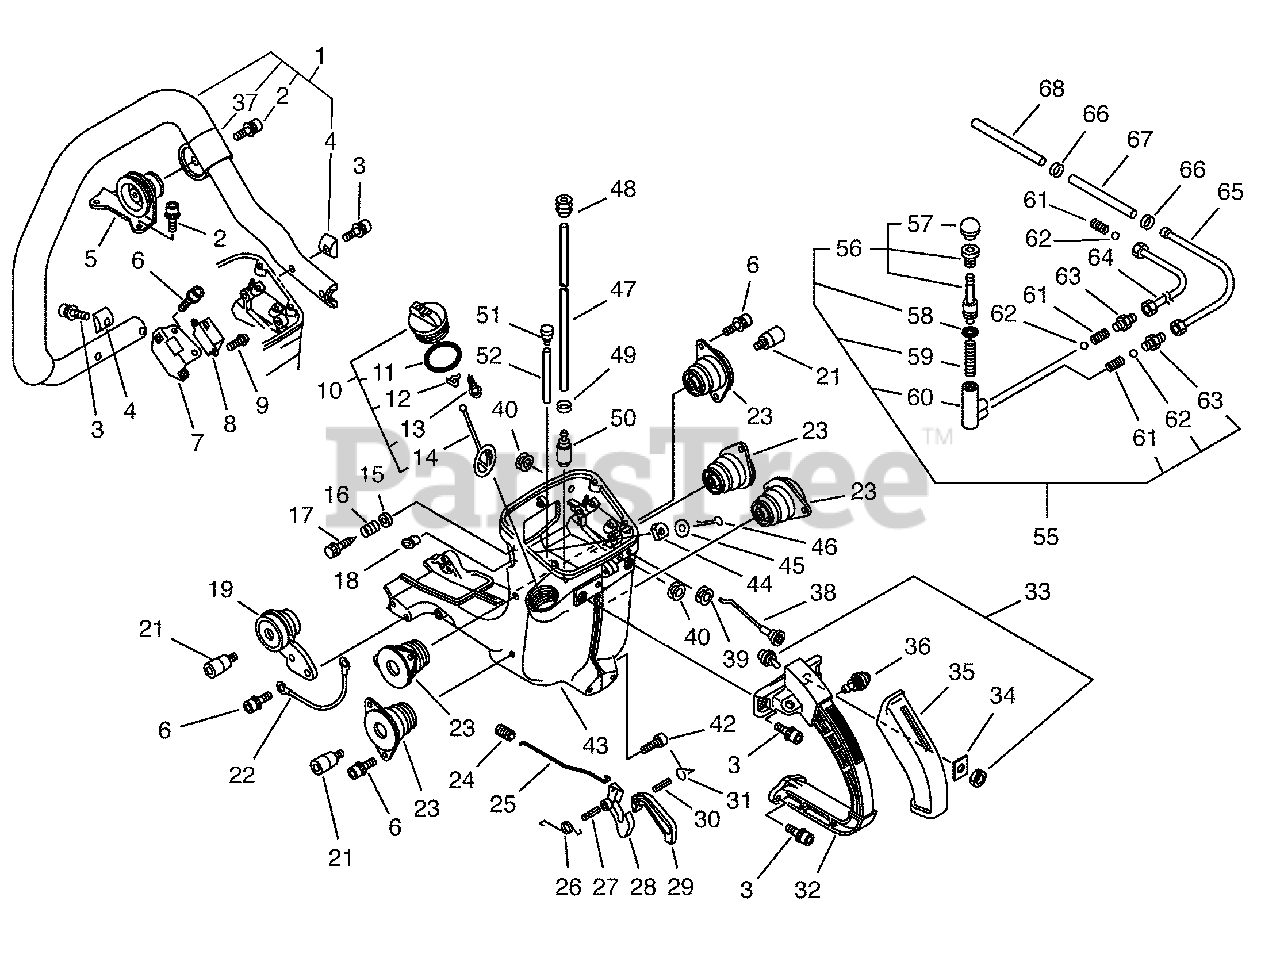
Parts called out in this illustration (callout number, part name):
1	HANDLE ASSY, FRONT
2	BOLT 6×20
3	BOLT 6×25
5	CUSHION
6	BOLT 5×14
7	BRACKET, MODULE
9	SCREW 5×10
10	CAP ASSY, FUEL
11	O-RING 32
12	RETAINER, CONNECTOR
13	SCREW, TAPPING 3×8
14	CONNECTOR, CAP L= 60 MM
15	WASHER 4 MM
16	SPRING, THROTTLE
18	GROMMET
21	FASTENER, CUSHION
22	LEAD - GROUND
23	CUSHION
24	GROMMET
25	ROD, THROTTLE
26	SPRING, THROTTLE RETURN
27	PIN, SPRING Ø5×25 MM
28	CONTROL, THROTTLE
29	LOCKOUT, THROTTLE
30	PIN, SPRING - 4×18
31	SPRING
33	SWITCH, ON-OFF
34	LABEL, ON-OFF
35	GRIP, REAR HANDLE
36	LATCH, THROTTLE
37	BRACKET, HANDLE
38	ROD, CHOKE
39	GROMMET, RUBBER
40	BUSHING
42	BOLT 5×14
43	TANK, FUEL
44	PACKING
45	WASHER 2 MM
46	PIN, COTTER
49	CLIP Ø6.5 MM
50	FILTER, FUEL
51	VENT ASSY
52	PIPE, VENT
55	OIL PUMP ASSY
56	PUMP PISTON
57	PUSH BUTTON
58	O-RING 6 MM
59	SPRING, OIL PUMP
60	BODY, OIL PUMP
61	SPRING, VALVE
62	VALVE, BALL
63	CONNECTOR
68	PROTECTOR, TUBE
